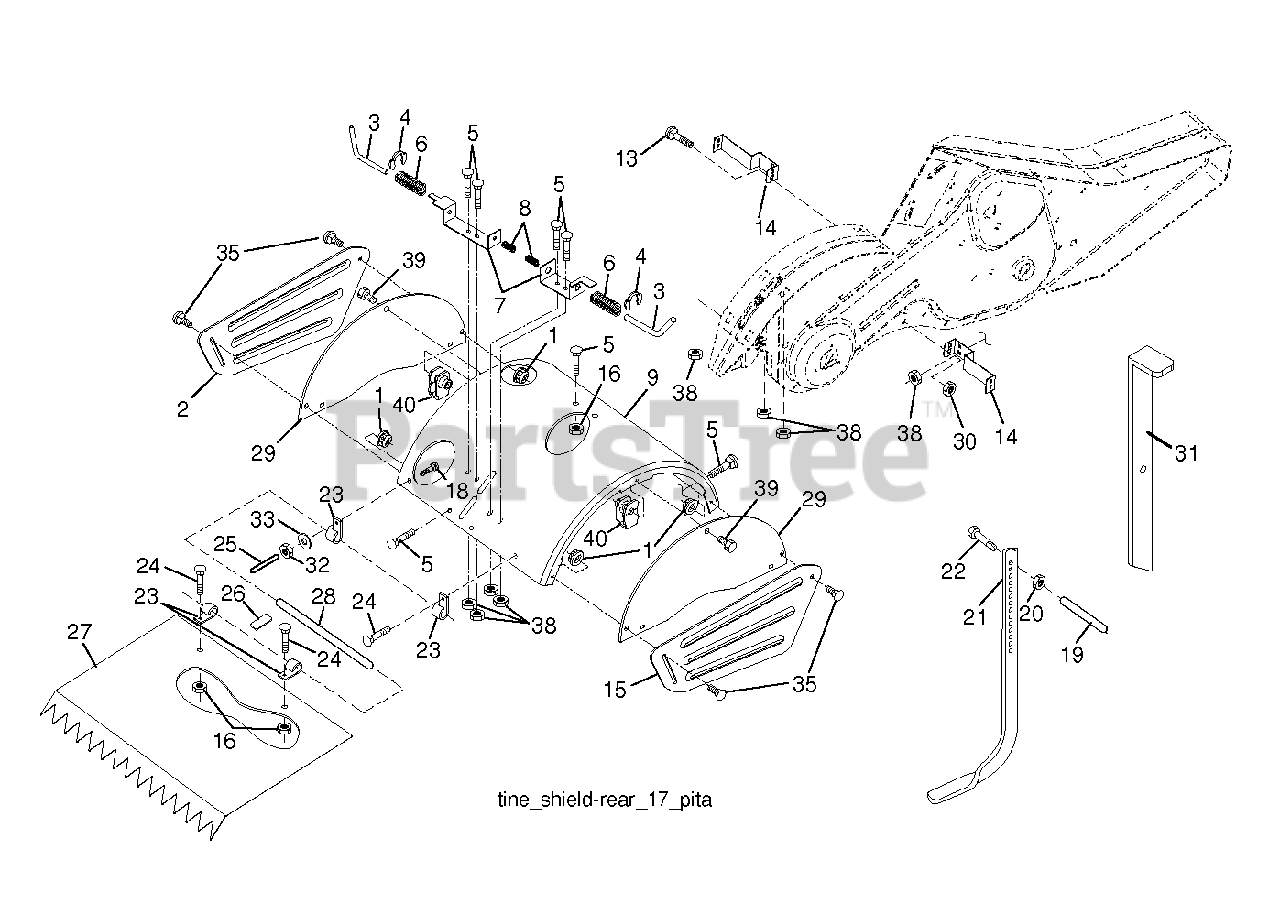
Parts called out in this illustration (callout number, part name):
1	NUT.FLANGE.5/16
3	STAKE PIN TI
4	RING, KLIP
5	BOLT, RDHD SQNK 5/16-18 X 3/4
6	SPRING TI
7	Latch Stake Bracket, 3 20 Black
8	SPRING CRT
13	BOLT.CARRIAGE.5/16-18
16	NUT T
20	NUT.HEX.3/8-16UNC
22	BOLT.375-16
23	HINGE CRT
25	VINYL CAP TI
26	PAD IDLER TI
28	PIN.HINGE.TILLER
29	RP.SHIELD.ASM.PNT.SIDE.RED
30	LOCKNUT-FLANGE 5/16-18
31	STAKE.DEPTH.DRAG.BLACK.TILLER
32	NUT
33	LOCKWASHER
35	BOLT
38	NUT
39	BOLT.HEX.HD.WASHER.5/16-18X.75
40	NUT, SPEED 5/16-18
